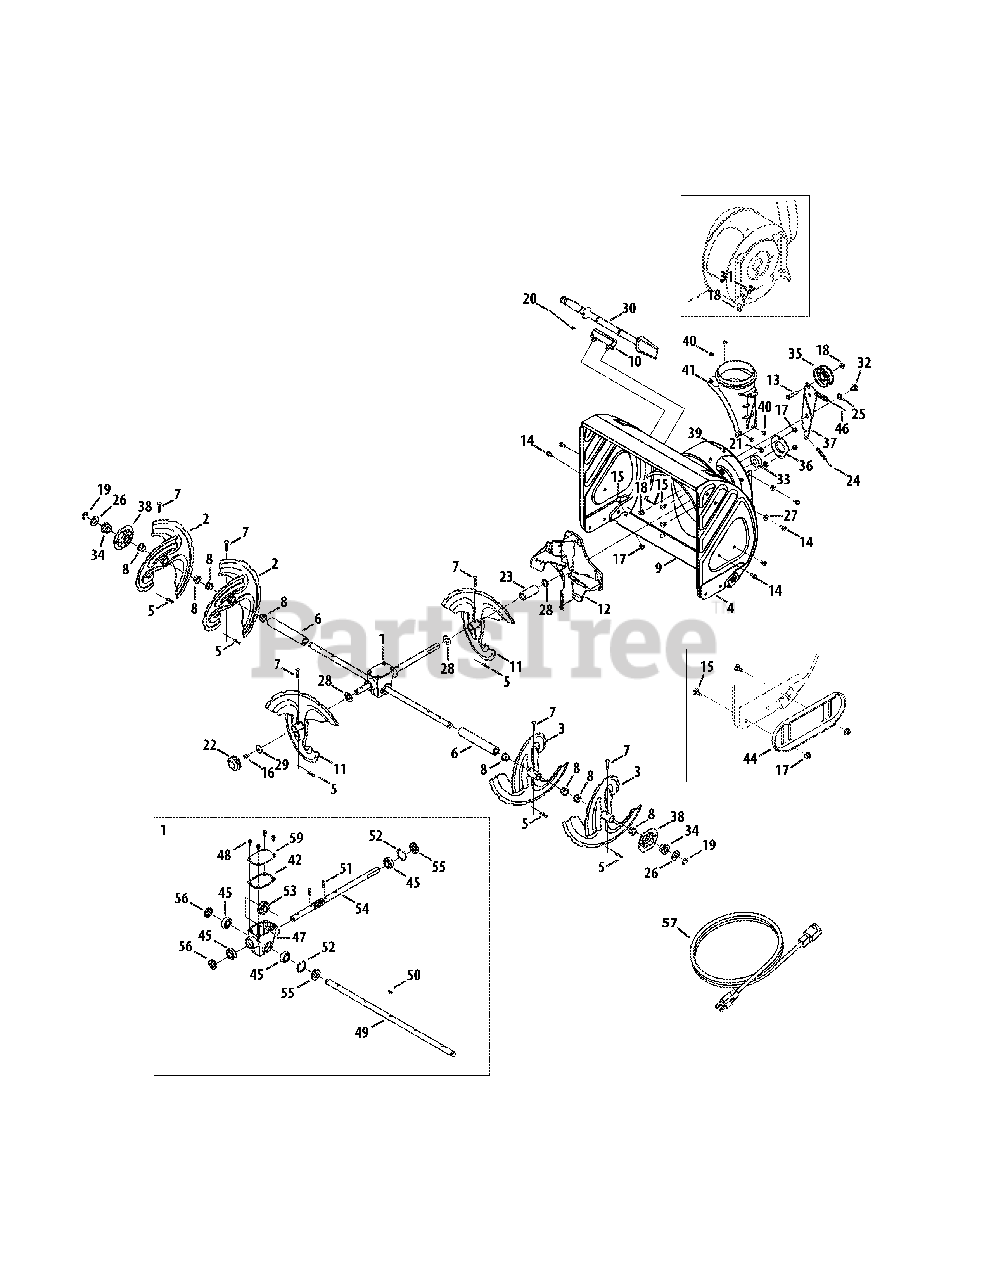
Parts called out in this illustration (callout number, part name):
1	Gearbox Assembly, Auger, 30"
2	Spiral Assembly - RH
3	Spiral Assembly - LH
4	Auger Housing, 30"
5	Bow Tie Cotter Pin
6	Spacer, 1.25 OD x .75 ID x 7.38
7	Shear Pin
8	Flange Bushing, .800 x .910
9	Shave Plate, 30"
10	Clean-out Tool Mtg. Bracket
11	Accelerator Assembly
12	Impeller Assembly
13	Hex Bolt, 3/8-16 x 1.75
14	Screw, 5/16-18 x .750
15	Carriage Bolt, 5/16-18 x .750
16	Hex Washer Screw, 5/16-18 x .500
17	Flange Lock Nut, 5/16-18
18	Flange Lock Nut, 3/8-16
19	E-ring, .75
20	Cable Tie
21	Push-On Nut, .25 Dia.
23	Spacer, 1.35 OD x .76 ID x 2.705
24	Extension Spring, .38 OD x 4.59
25	Wave Washer, .625 x .885 x .0175
26	Flat Washer, .76 x 1.49 x .06
27	Bell Washer, .340 x .872 x .060
28	Flat Washer, .793 x 1.24 x .06
29	Flat Washer, .406 x 1.92 x .060
30	Clean-Out Tool
31	Shoulder Screw, 3/8-16 x .496 x .336
32	Shoulder Screw, 3/8-16 x .625 x .17
33	Flange Ball Bearing, .75 x 1.85
34	Hex Flange Bearing, .75 ID
35	Flat Idler Pulley
36	Bearing Housing
37	Auger Idler Bracket
38	Bearing Housing
39	Carriage Screw, 1/4-20 x 0.75
40	Flange Lock Nut, 1/4-20
41	Chute Adapter
42	Gearbox Gasket
43	Gearbox Cover
44	Skid Shoe, Deluxe Steel
44	Skid Shoe Kit, Polymer Reversible Deluxe
45	Ball Bearing, .75 x 40 x 12
46	Auger Clutch Cable
47	Auger Housing
48	Screw, 1/4-20 x 0.75
49	Axle, Auger, 30"
50	Hi-Pro Key
51	Pin, Roll, .25 x 1.0
52	Retainer Ring
53	Worm Gear, 20T
54	Worm Shaft
55	Seal, .75 x 40mm x .25
56	Seal, .75 x 1.375 x .25
57	3-Prong Extension Cord
